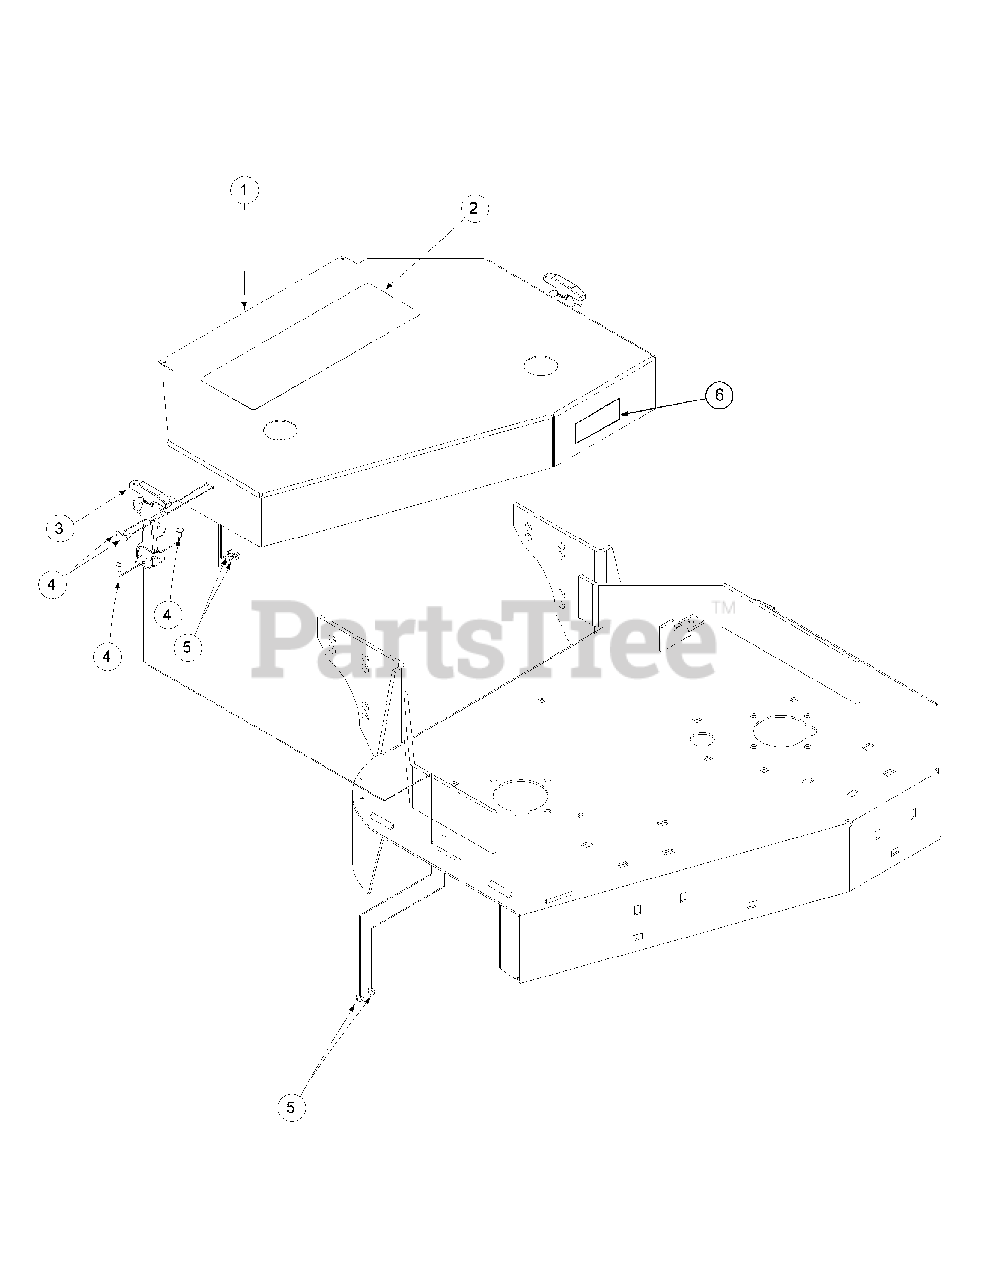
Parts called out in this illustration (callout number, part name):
1	Deck Cover, 32"
2	Label Commercial Mower
3	Rubber Hood Latch
4	Machine Screw, 10-24 x 1/2
5	Lock Nut, Nylon Insert, 10-24
6	Label, G1332
